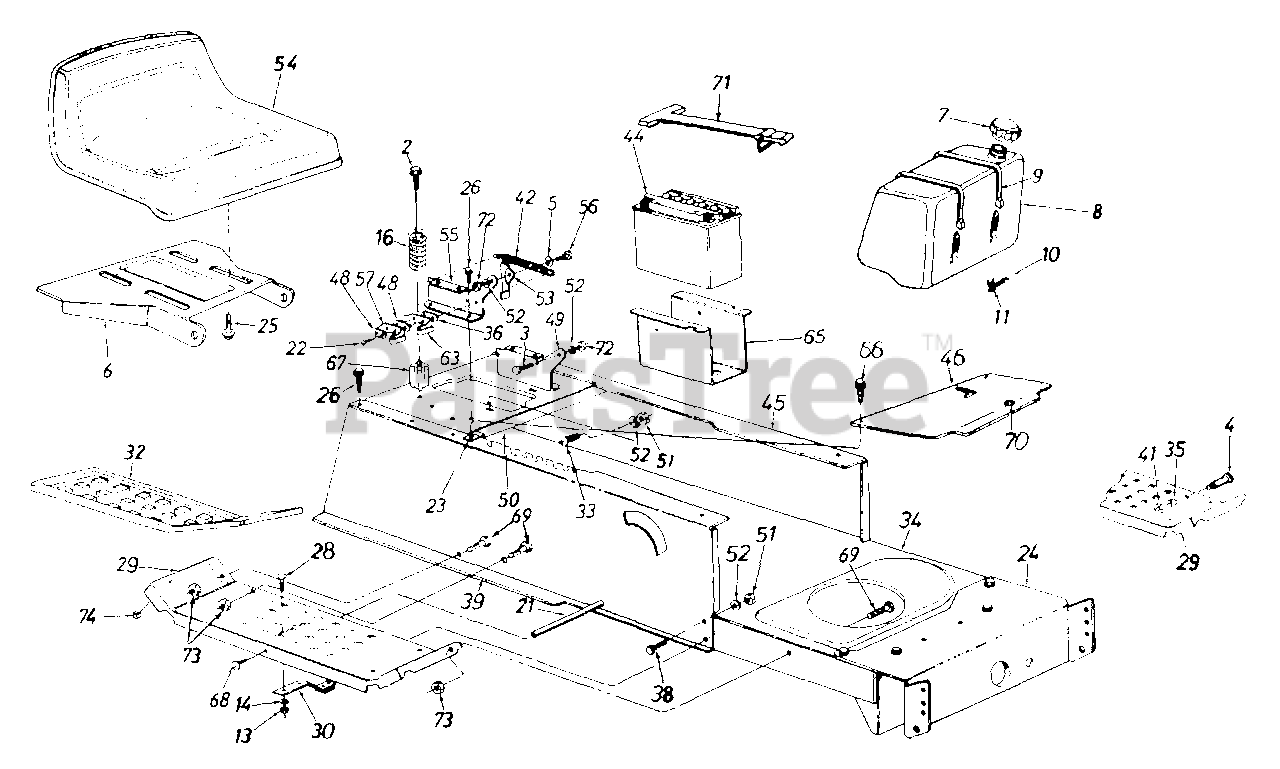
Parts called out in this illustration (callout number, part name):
2	Hex Wash. Hd. Tap Scr. 5/16-18 x 3.25" Lg.
3	Shld. Bolt .437" Dia. x .162"
4	Shld. Bolt .50" Dia. x .84"
5	Spr-Wash. .445" I.D. x .75
7	Fuel Cap
8	Fuel Tank (LT-125)
9	Tie Strap
10	Fuel Line
13	Hex Nut 1/4-20 Thd. (Gr. 5)
14	L-Wash. 1/4" I.D.
16	Compression Spring
21	Running Board Rod
22	Hex Wash. Hd. AB-Tap Scr. #8 x .50" Lg.
23	Speed Nut #10Z
25	Hex Tap Scr. 3/8-16 x .62"
26	Hex AB-Tap Scr. 5/16 x .75" Lg.
28	Carriage Bolt 1/4-20 x .62"
32	Rubber Foot Pad - L.H.
33	Truss Mach. Scr. 5/16-18 x .75"
35	L-Wash. 3/8" I.D.
36	Insulator Boss Plate
38	Hex Bolt 5/16-18 x .75" Lg.
42	Extension Spring 5.31" Lg.
44	12-V Battery (LT-125)
52	L-Wash. 5/16" I.D.
53	Seat Lift Brkt.
54	Seat (LT-125/LT-155)
56	Shld. Bolt .437" Dia. x .268"
57	Spring Switch
63	Safety Switch (Seat)
66	Truss Mach. B-Tap Scr. #10 x .5" Lg.
67	Spring Spacer
68	Pan Hd. Scr. 5/16-18 x .75" Lg.
69	Hex Bolt 5/16-18 x .75" Lg.
70	Snap Bushing
71	Battery Retainer Strap
72	Hex Nut 5/16-18 Thd. (Gr. 5)
73	Hex Sems Nut 5/16-18 Thd.
74	Hex Sems Nut 1/4-20 Thd.
